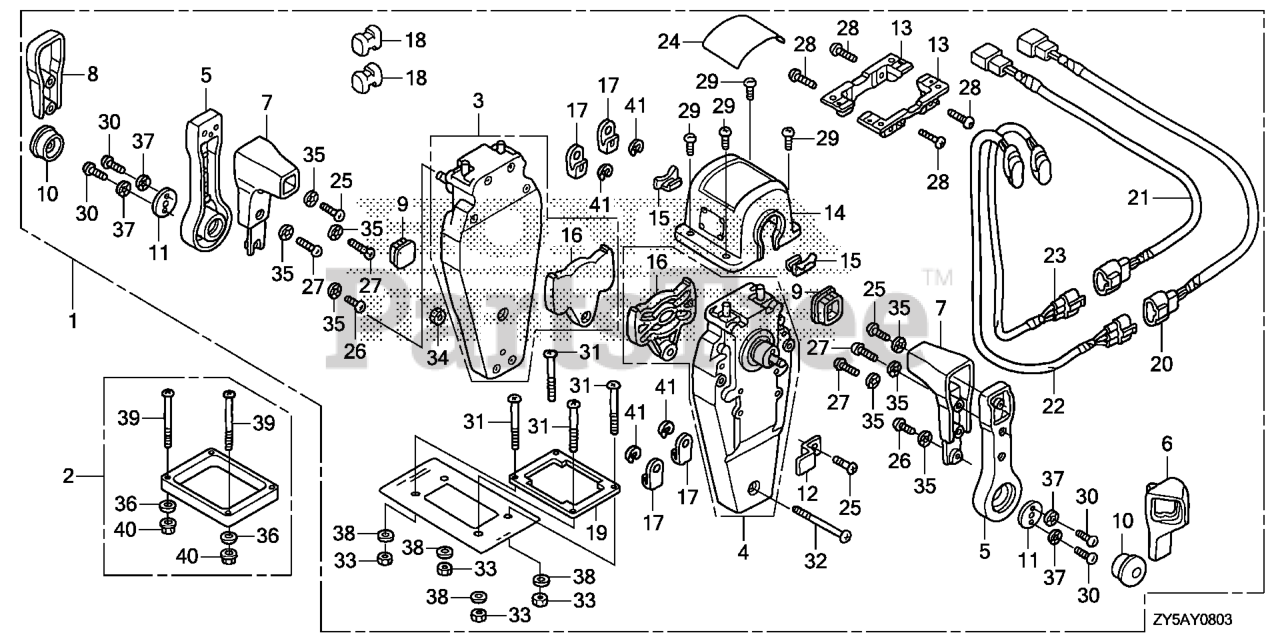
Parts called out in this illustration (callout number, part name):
1	BOX KIT, REMOTE CONTROL (TOP MOUNT DUAL)(L)
2	SPACER KIT, REMOTE CONTROL BOX (TOP MOUNT DUAL)
3	HOUSING ASSY., L. (INNER) (TOP MOUNT)
4	HOUSING ASSY., R. (INNER) (TOP MOUNT)
5	HANDLE, REMOTE CONTROL
6	COVER, R. GRIP
7	GRIP, REMOTE CONTROL HANDLE
8	COVER, DUAL GRIP
9	CAP, GRIP
10	BUTTON, THROTTLE
11	PLATE, HANDLE
12	PLATE, CABLE CLAMP
13	BRACKET, REMOTE CONTROL HOUSING
14	HOUSING, DUAL REMOTE CONTROL BOX
15	HOUSING, LEAD
16	PLATE, DWELL
17	TERMINAL, CABLE
18	SPACER, CABLE CLAMP
19	GASKET, DUAL
20	SUB-HARNESS ASSY., POWER TRIM-TILT (A)
21	SUB-HARNESS ASSY., POWER TRIM-TILT (B)
22	SWITCH ASSY., POWER TRIM-TILT (A)
23	SWITCH ASSY., POWER TRIM-TILT
24	MARK, REMOTE CONTROL (DUAL)
25	SCREW, PAN (5X16)
26	SCREW, PAN (5X10)
27	SCREW, PAN (5X20)
28	SCREW, PAN (5X18)
29	SCREW, PAN (4X10)
30	SCREW, PAN (6X18)
31	SCREW, PAN (5X40)
32	SCREW, PAN (5X55)
33	NUT, HEX. (5MM)
34	NUT, HEX. (5MM)
35	WASHER, LOCK (5MM)
36	WASHER, PLAIN (5MM)
37	WASHER, LOCK (6MM)
38	WASHER, PLAIN (5MM)
39	SCREW, PAN (5X65)
40	NUT, HEX. (5MM)
41	E-RING (6MM)
